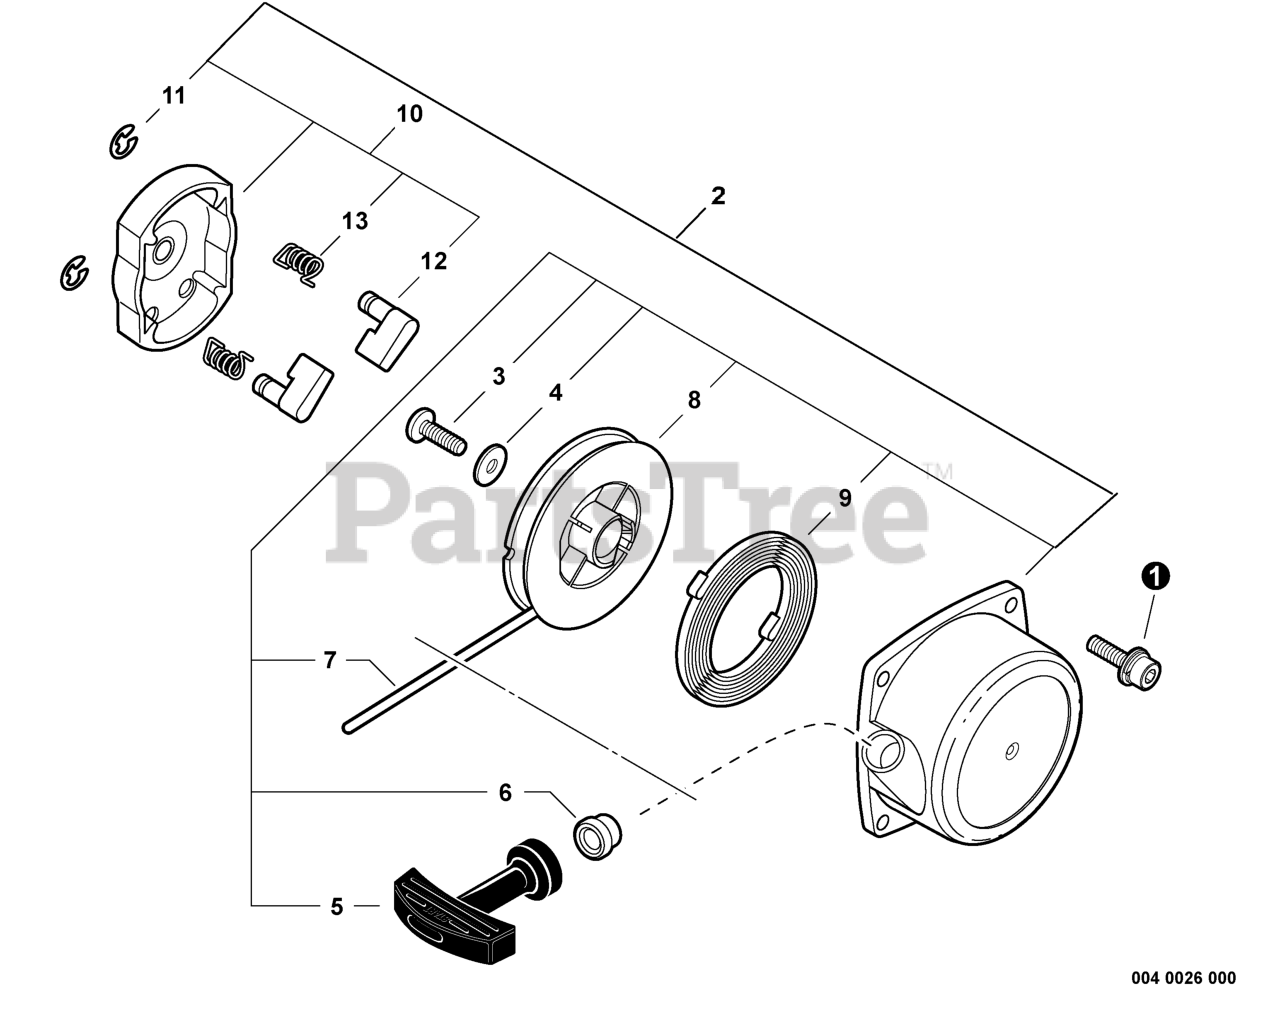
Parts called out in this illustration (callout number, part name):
1	SCREW - 4X18
2	STARTER ASSY
4	WASHER
5	GRIP, STARTER
6	GUIDE, ROPE
7	ROPE, STARTER - 4X1110
8	REEL, ROPE
9	SPRING, REWIND
10	STARTER PAWL ASSY
11	RING, RETAINING - 4
12	PAWL, STARTER
13	SPRING, RETURN
